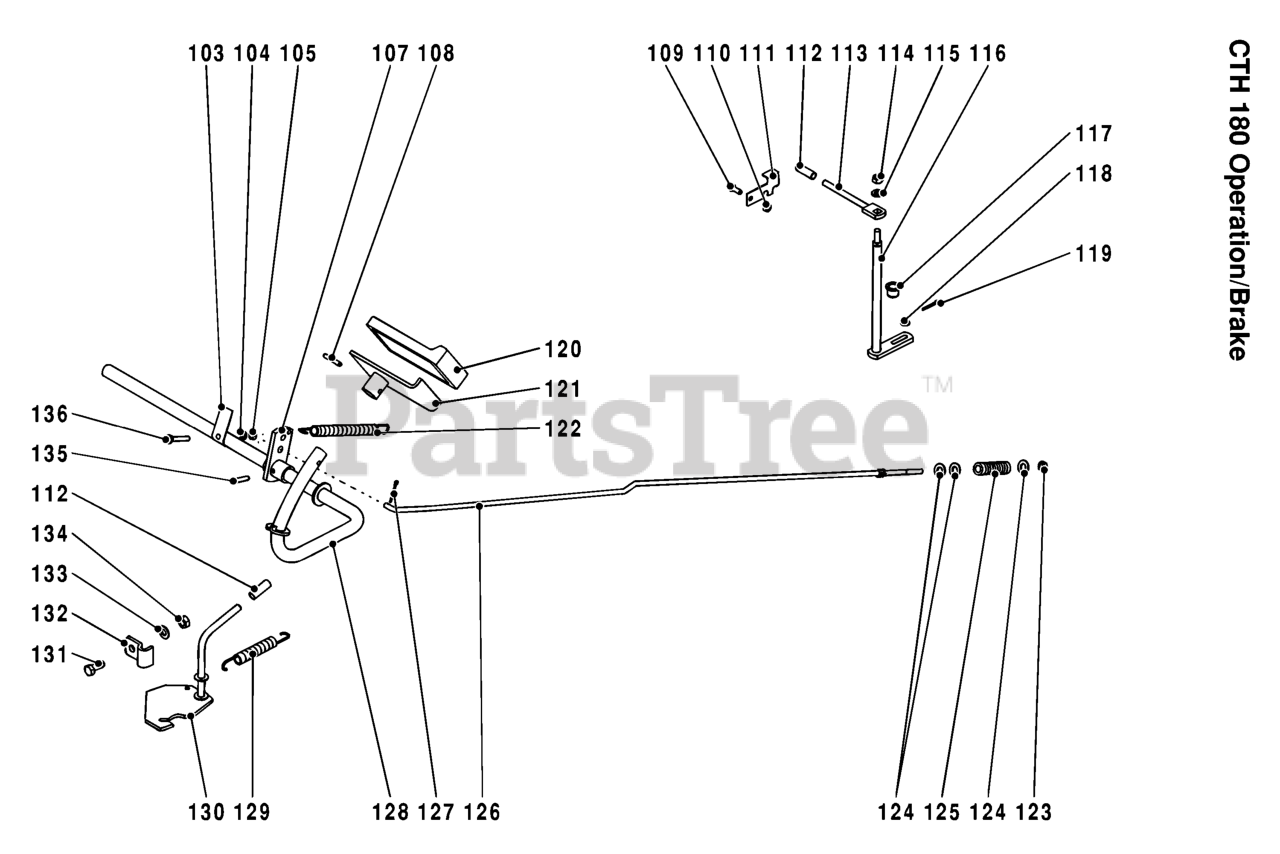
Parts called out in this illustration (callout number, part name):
109	BOLT FLANGE - M6X20
110	Blocking nut M 6 Z
114	NUT
118	WASHER - M6
123	NUT
134	NUT
